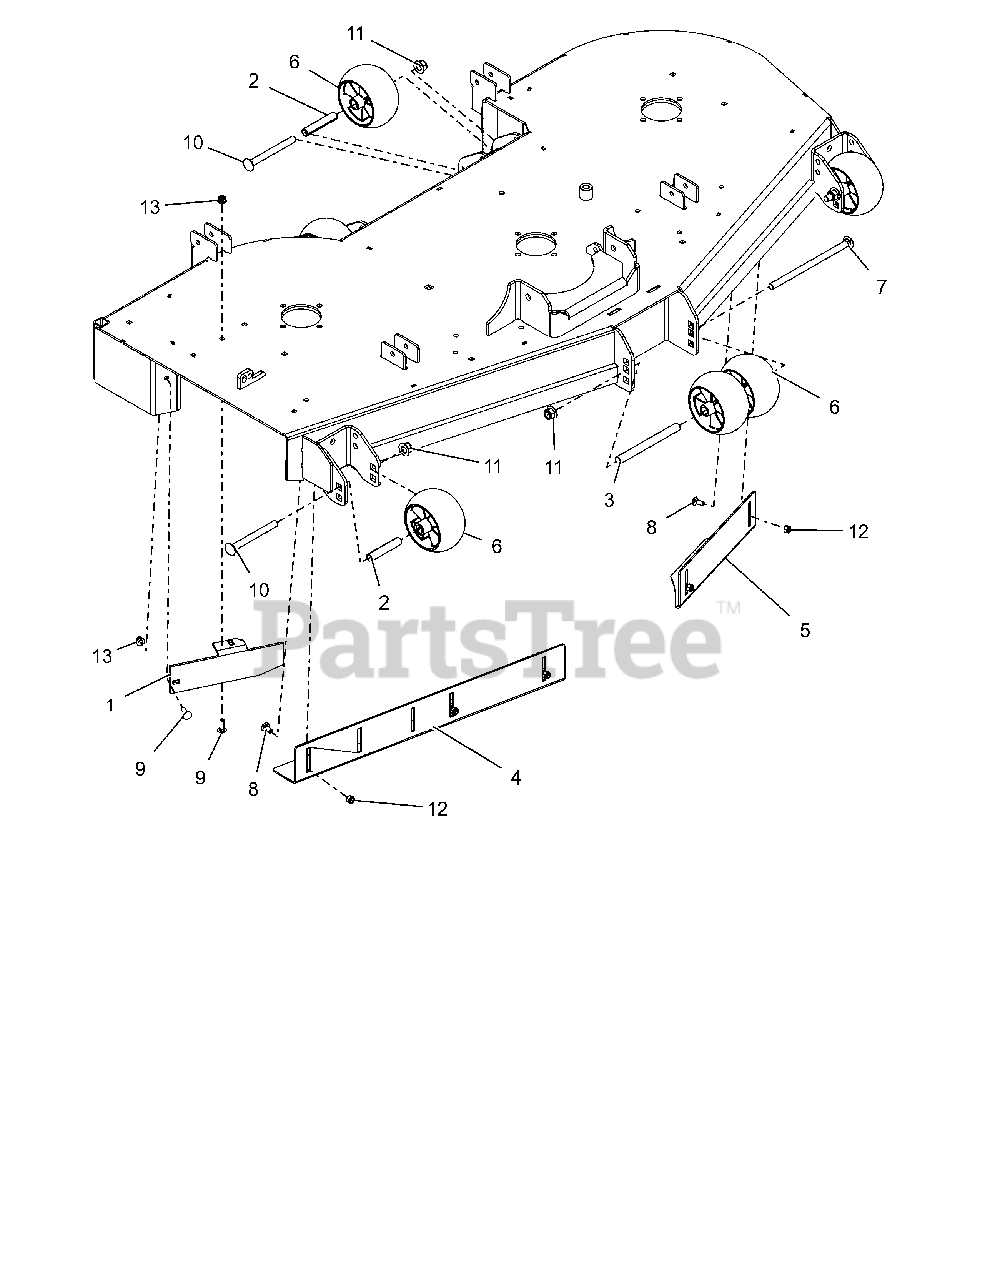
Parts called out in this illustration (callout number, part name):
1	60" DISCHARGE BAFFLE - RED
2	SPACER, .510X.625X3.35
3	SPACER, .510X.625X6.50
4	60" RH VACUUM BAFFLE - BLK
5	60" LH VACUUM BAFFLE - BLK
6	ANTI-SCALP WHEEL - 5X3 CTR
7	@BLT-RDHDSQNK .50-13X8.50 G5YZ
8	@BLT-RDHDSQNK .31-18X.75 G5YZ
9	@BLT-RDHDSQNK .31-18X1.00 G5YZ
10	BLT-RDHDSQNK .50-13X5.00 GR5YZ
11	@NUT-LK-NYL-FLG .50-13 YWZC
12	@NUT-LK-NYL .312-18 YWZC
13	@NUT-LK-NYL-FLG .31-18 YWZC
